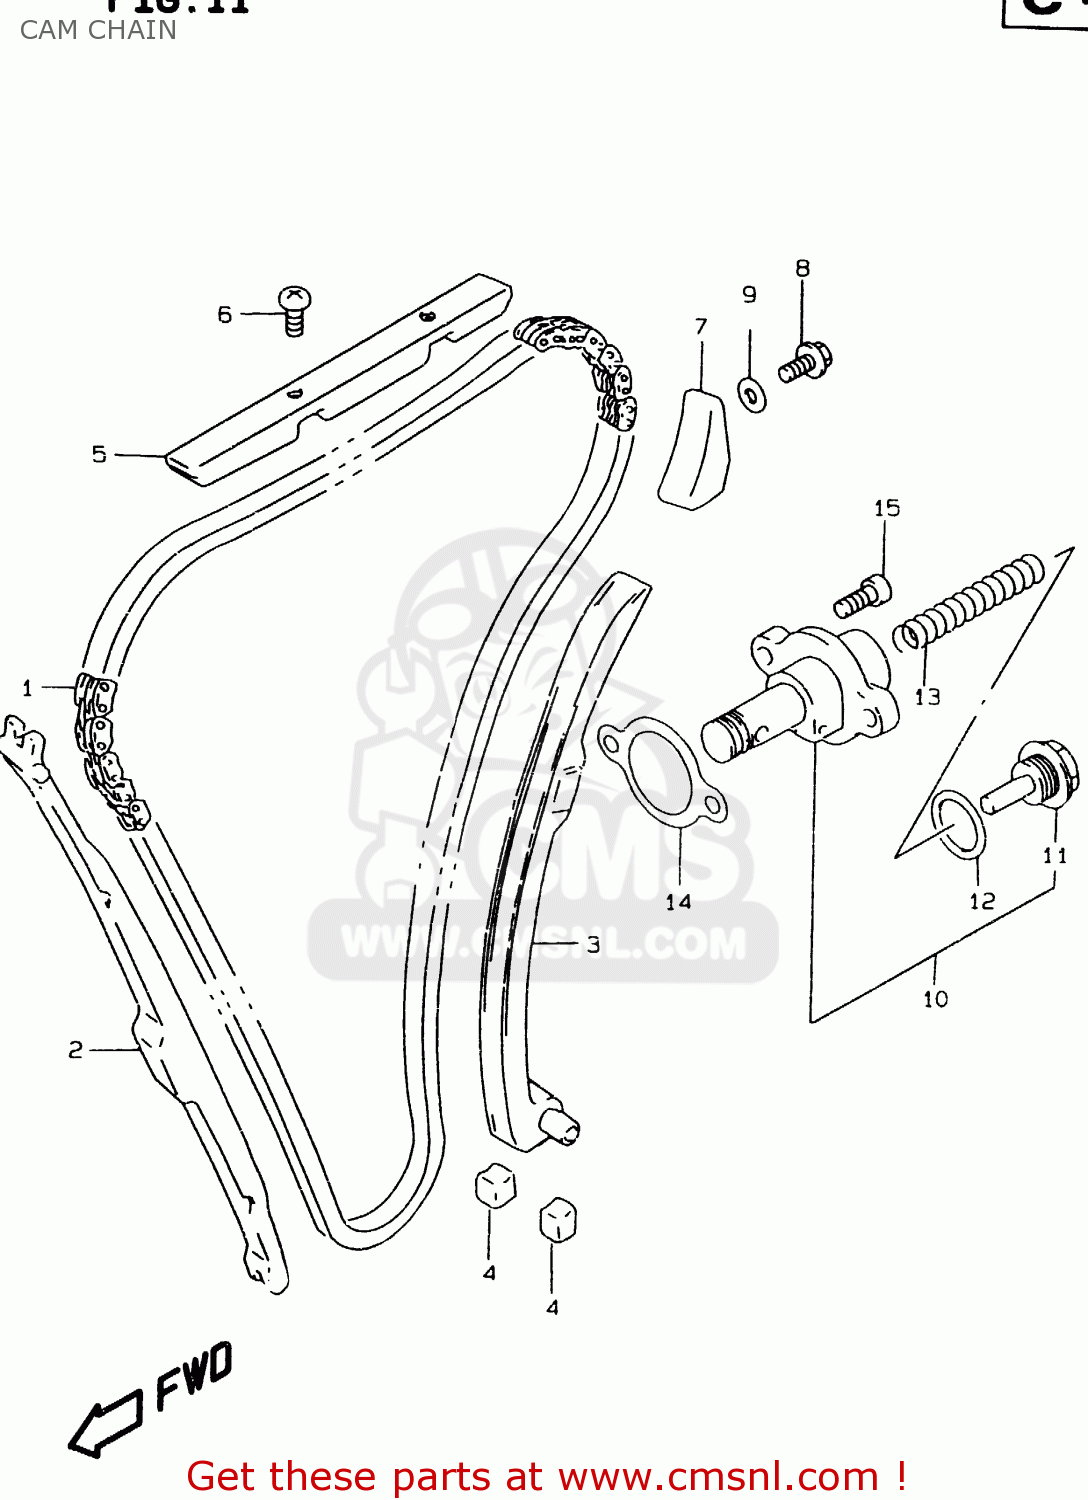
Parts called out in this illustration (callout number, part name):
1	CHAIN,CAMSHAFT DRIVE
2	GUIDE,CAM CHAIN NO.1
3	TENSIONER,CAM CHAIN
4	CUSHION,CAM CHAIN TENSIONER
5	GUIDE,RR CAM CHAIN NO.1
6	SCREW
7	GUIDE,CAM CHAIN NO.2
8	BOLT
9	GASKET(5.8X13X1.2) (NAS)
10	ADJUSTER ASSY,TENSIONER
11	PLUG
12	GASKET (NAS)
13	SPRING
14	GASKET,TENSIONER ADJUSTER (NAS)
15	BOLT,CL.COVER
